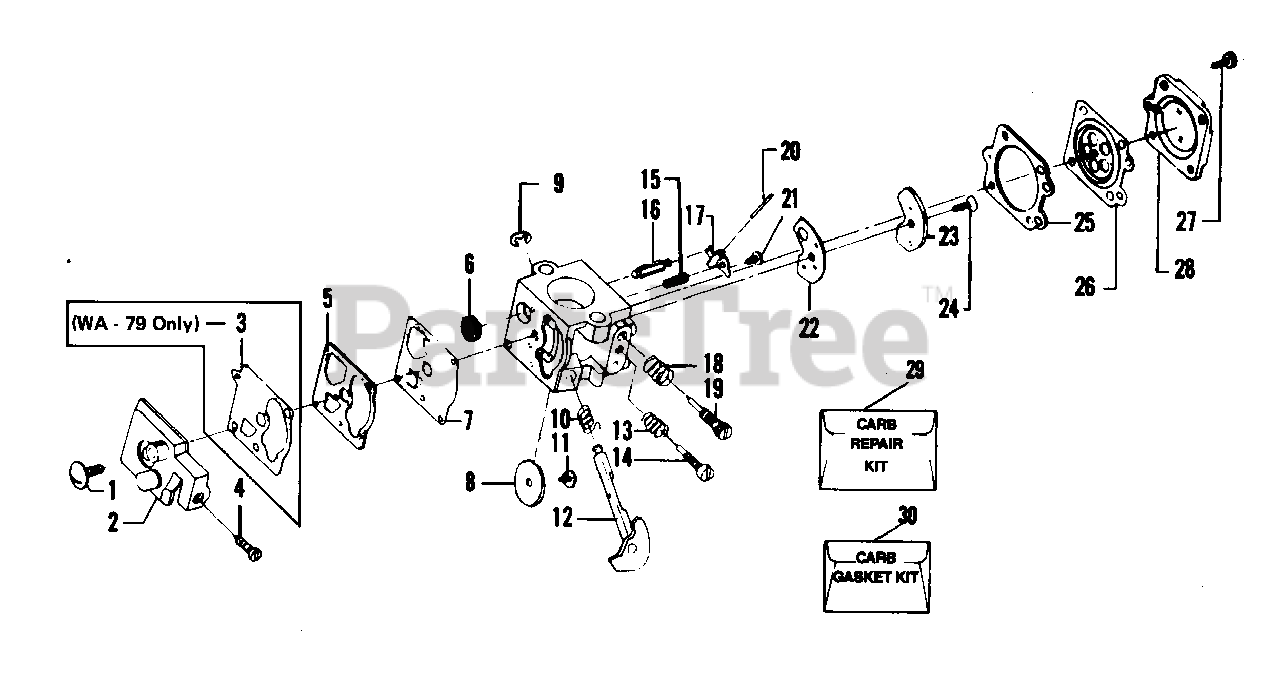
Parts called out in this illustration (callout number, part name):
1	Screw - Pump Cover
2	Pump Cover Ass'y (Inc. #4) WA-79
2	Pump Cover Ass'y (Inc. #4) WA-149
3	Diaphragm - Pump WA-79
4	Screw - Idle Adjustment
5	Gasket - Pump WA-79
5	Gasket - Pump WA-149
6	Screen - Inlet
7	Diaphragm - Pump WA-79
7	Diaphragm - Pump WA-149
8	Valve - Throttle
9	Clip - Throttle Shaft
10	Spring - Throttle Return
11	Screw - Throttle Valve
12	Shaft Ass'y - Throttle
13	Spring - Idle Needle
14	Needle - Idle
15	Spring - Metering Lever
16	Valve - Inlet Needle
17	Lever - Metering
18	Spring - Hi Speed Needle
19	Needle - Hi Speed
20	Pin - Metering Lever
21	Screw - Metering Lever Pin
22	Gasket - Circuit Plate
23	Plate - Circuit
24	Screw - Circuit Plate
25	Gasket - Metering Diaphragm
26	Diaphragm Ass'y - Metering
27	Screw - Ass'y - Metering Cover & Throttle Shaft Clip
28	Cover - Metering Diaphragm
29	Kit-Carb Repair WA-79
29	Kit-Carb Repair WA-149
30	Kit-Carb Gasket/Diaphragm WA-79
30	Kit-Carb Gasket/Diaphragm WA-149
